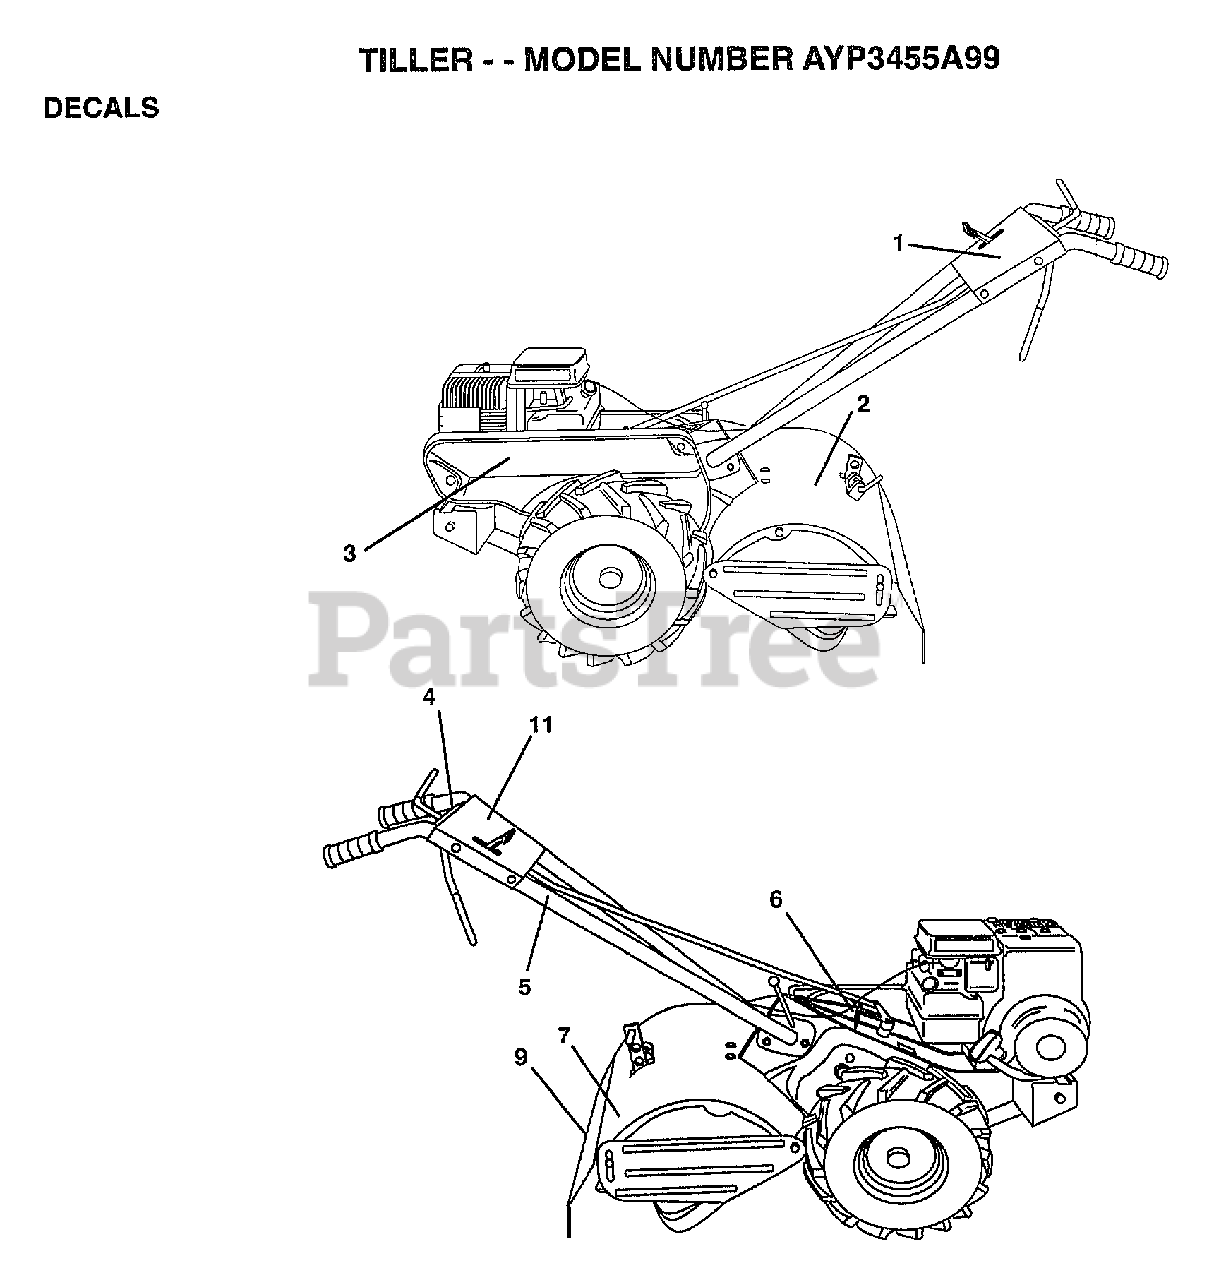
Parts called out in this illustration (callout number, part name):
3	DECAL, LOGO
5	DECAL TI
6	DECAL CRT
7	DECAL.TINE.SHIELD
9	DECAL TI
11	DECAL REVERSE
